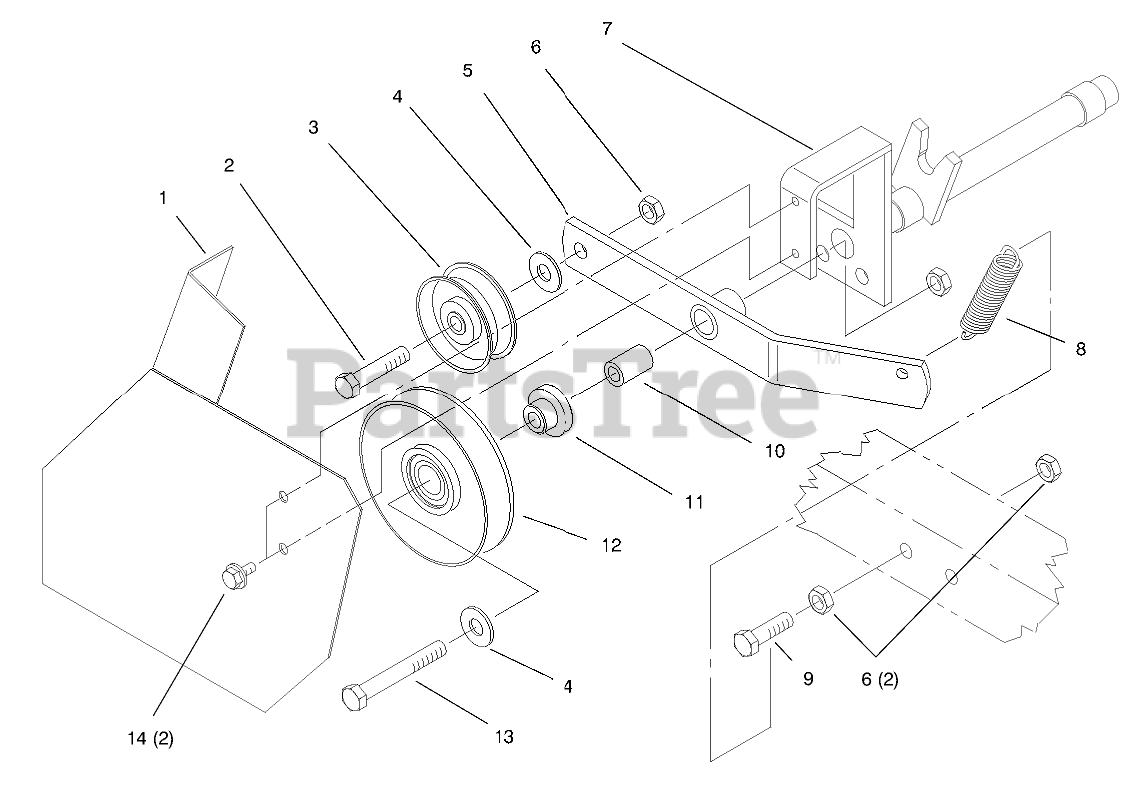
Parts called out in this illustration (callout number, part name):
1	ASM: FRONT IDLER R
2	SCREW-HH
3	IDLER PULLEY
4	WASHER-FLAT
5	ASSY IDLER ARM R
6	NUT-HEX
7	ASSY SUPPORT R
8	SPRING-BRAKE
9	SCREW-HH
10	SPACER
11	SPACER
12	PULLEY-IDLER
13	SCREW-HH
14	SCREW-HWH
